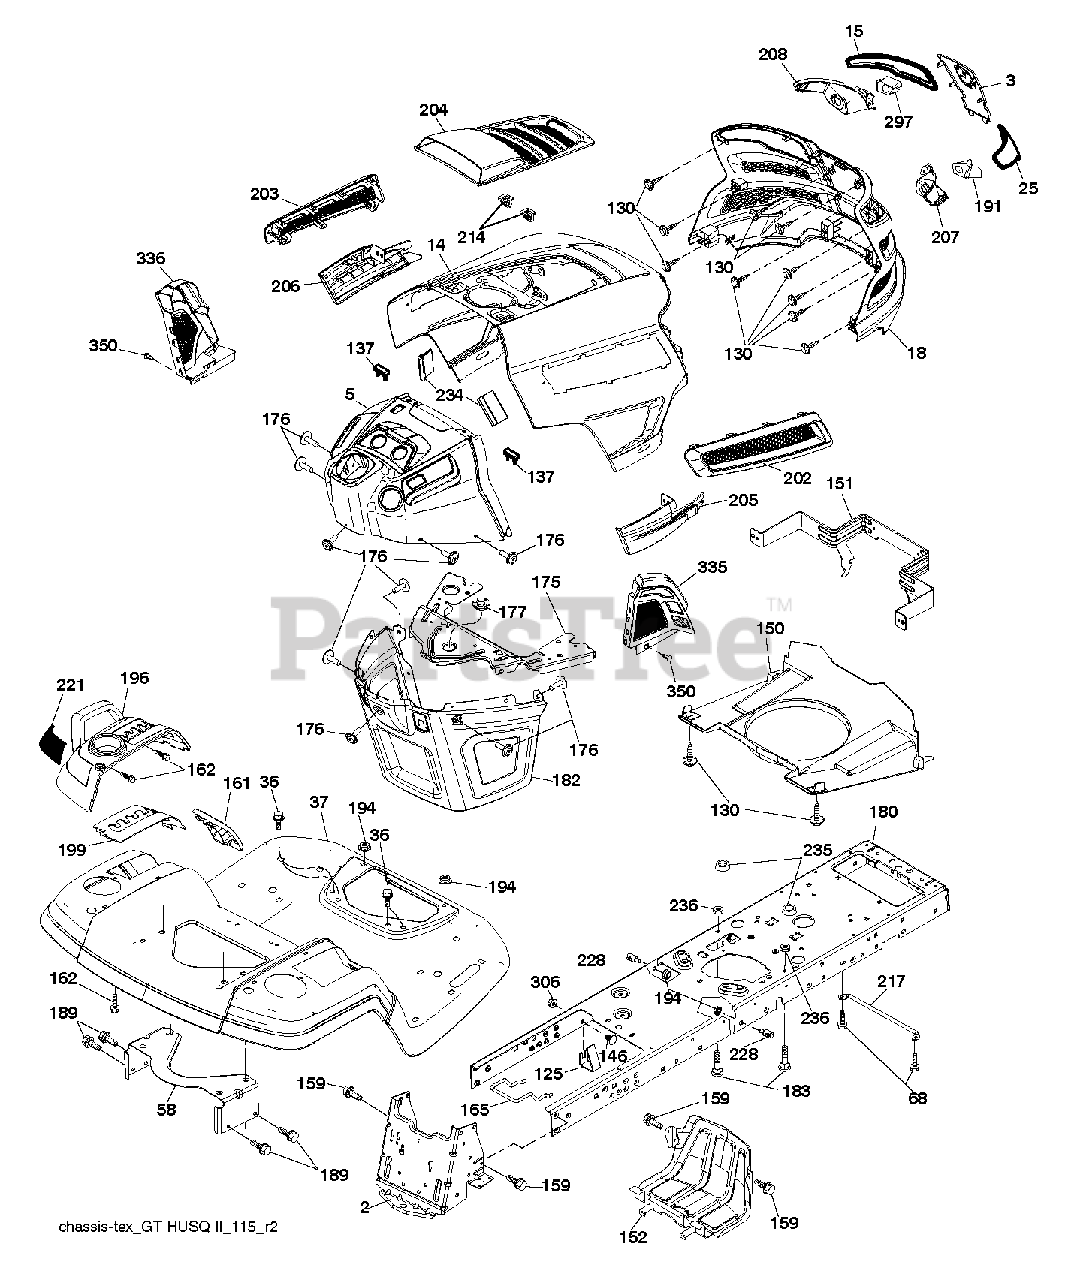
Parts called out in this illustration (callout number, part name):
2	DRAWBAR.STGT
3	APPLIQUE.SUBASM.GT.HUSQ.II
5	UPPER.GT2.DUAL.ROUND.PTO.ELECT
14	HOOD.ASM.HUSQVARNA.GT.TEX.ORAN
15	LENS.HEADLIGHT.LH.GTII.2011
18	GRILLE.SUBSTRATE.2011.
25	LENS.HEADLIGHT.RH.GTII.2011
36	SCREW 5/16"
37	FENDER.PNT.TX.GT.CH/FW/DL.HUSQ
58	BRKT.SUPPORT.FNDR/TANK
68	SCREW LT
125	CLIP.FUEL.LINE
130	SCREW.#10 X 0.750.BOS
137	BUMPER DASH
146	BOLT.RDHD.SHT.SQNK.3/8-16X5/8
150	AIR.DUCT.GTV.BLACK
151	BRACKET.PIVOT.HOOD.GT.HUSQ.II
152	SHIELD.BROWNING.PNT.GT.V2
159	SCREW, 3/8-16X3/4
161	CONSOLE.WINDOW.FUEL.HUSQ.GT
162	SCREW.HI-LO.CONSOLE
165	SUPPORT.TANK.REAR.B/TE
175	PLATE.CROSSMEMBER.HUSQ
176	SCREW.#10-24X5/8.RN.QU
177	BUSHING, STEERING
180	CHASSIS.TEX.BOLTED
182	DASH.LOWER.COMMON.12V.ADAPTOR
183	BOLT.5/16-18X1-1/4 FULL THD
189	SCREW
191	INSERT.REFLECTIVE.RH.HUSQ.GTII
194	NUT LOCK HEX FLANGE 5/16-18
196	CONSOLE.ASM.DECKLIFT.HUSQGT.DL
199	PLATE.DECK.LIFT.HUSQVARNA.GT
202	VENT.SIDE.RH.GT.HUSQ.II.
203	VENT.SIDE.LH.GT.HUSQ.II.498
204	VENT.TOP.HUSQ.GT2
205	SIDE.TRIM.RH.GT.HUSQ.II
206	SIDE.TRIM.LH.GT.HUSQ.II.GRAY
207	BEZEL LIGHT.RH.GT.II.MYLAR
208	BEZEL LIGHT.LH.GT.II.MYLAR
214	CLIP.RETAINER.TINNER.
217	ROD.PIVOT.HOOD
221	REFLECTOR.LH.TEX GT HU
228	STUD.FASTNER.W/ANTI-ROTATE
234	BUMPER.HOOD.TEX.HUSQVARNA
235	SPACER FENDER
236	NUT.CENTERLOCK.5/16-
297	INSERT.REFLECTIVE.LH.HUSQ.GTII
306	NUT LOCK FLG 3/8-16 UNC
335	COVER.LOWER.DASH.RH.BLACK
336	COVER-LH.LOWER.DASH.GT2.BLACK
350	CLIP.X-MAS.TREE
